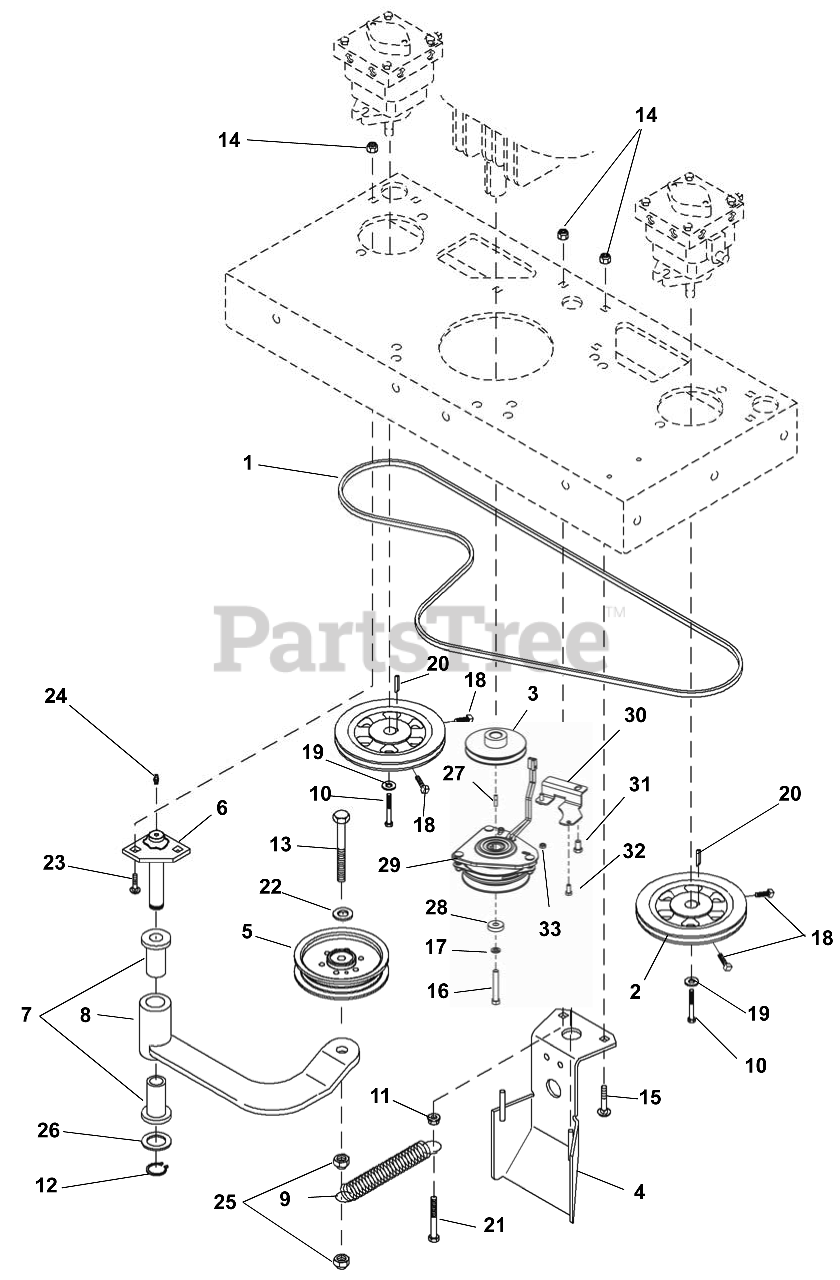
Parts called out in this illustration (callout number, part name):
1	V-BELT
2	PULLEY, RH PUMP SET SCREW INCL
3	PULLEY, ENGINE DRIVE
4	BRACKET
5	IDLER
6	IDLER POST
7	BUSHING
8	IDLER ARM
9	SPRING, IDLER
10	BOLT, M6X1.00X10 HEX 8.8 Y
11	LOCKNUT, M10X1.50 WHIZ GR10 Y
12	RG-RTNG-EXT .750X.042
13	@BLT-HEX .38-16X2.50 GR5 YWZC
14	NUT-LK-NYL M10-1.5 YWZC
15	CARRIAGE BOLT, M10 X 1.5 X 25
16	BLT-HEX .44-20X3.00 GR5 YWZC
17	@WSHR-LK .44X.109 REG YWZC
18	SET SCREW
19	WSHR-LK .250X.077 HVY YWZC
20	KEY, SPECIAL M5 X 28
21	CAP SCREW, SPRING ANCHOR M10 X
22	@WSHR-FL-STL.406X.812X.065 YWZ
23	CARRIAGE BOLT, M10 X 1.5 X 25
24	LUBRICATION FITTING
25	@NUT-LK-CTR .38-16 YWZC
26	BUSHING, 3/4 MACHINE
27	KEY, .250 X .250 X .995 TPR
28	SPACER, PTO CLUTCH
29	CLUTCH ASSY, OGURA
30	PLATE, CLUTCH DOG
31	@BLT-HEX .44-14X.75 GR5 YWZC
32	@BLT-HEX .31-18X.75 GR5 YWZC
33	@NUT-LK-NYL .312-18 YWZC
